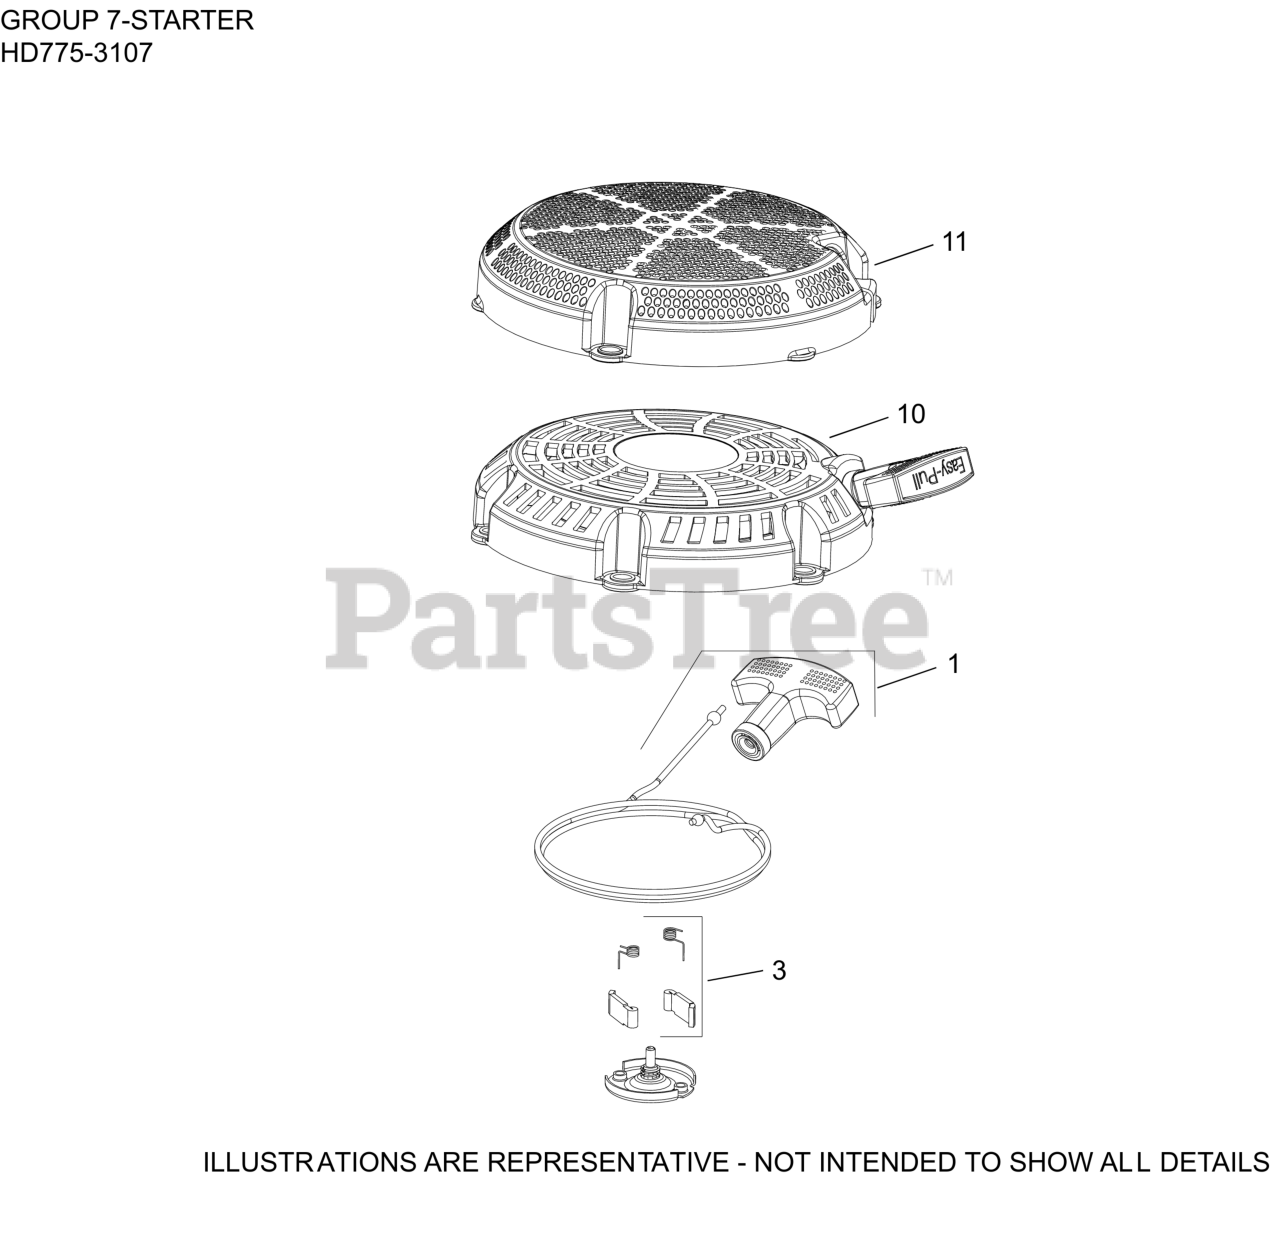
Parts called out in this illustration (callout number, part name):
1	KIT, STARTER ROPE W/HANDLE
3	KIT, PAWL REPAIR
10	STARTER ASSEMBLY, RETRACTABLE
11	INSERT, DEBRIS SCREEN
